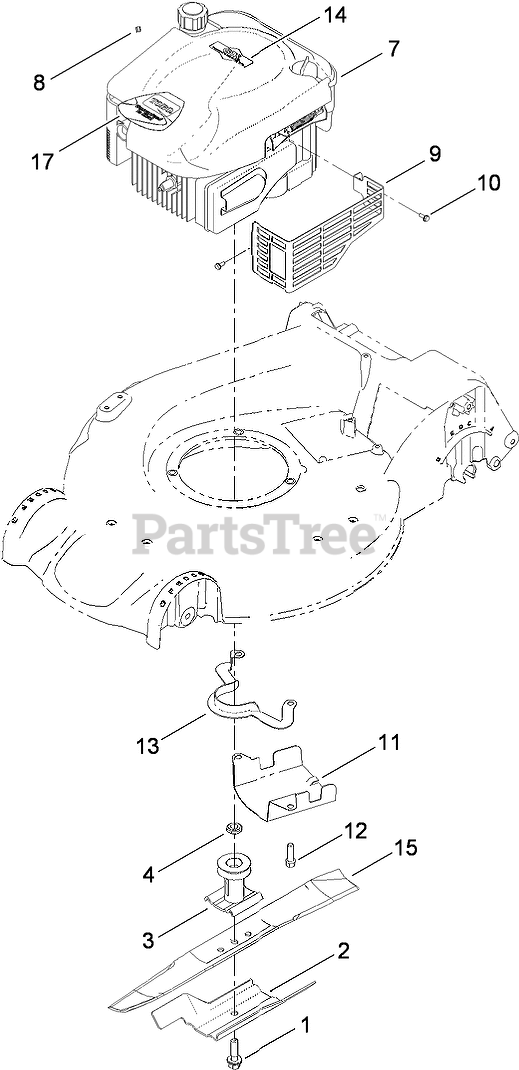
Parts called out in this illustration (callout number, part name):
1	BOLT-BLADE
2	Accelerator-Blade
3	DRIVER-BLADE
4	Spacer-Driver
8	STOP-ROPE
9	SHIELD-MUFFLER
10	SCREW-TAPTITE
11	SHIELD-GRASS
12	SCREW-TAPTITE
13	GUIDE-BELT
14	DECAL-RECOIL
15	BLADE-RECYCLING
17	DECAL-SHROUD
